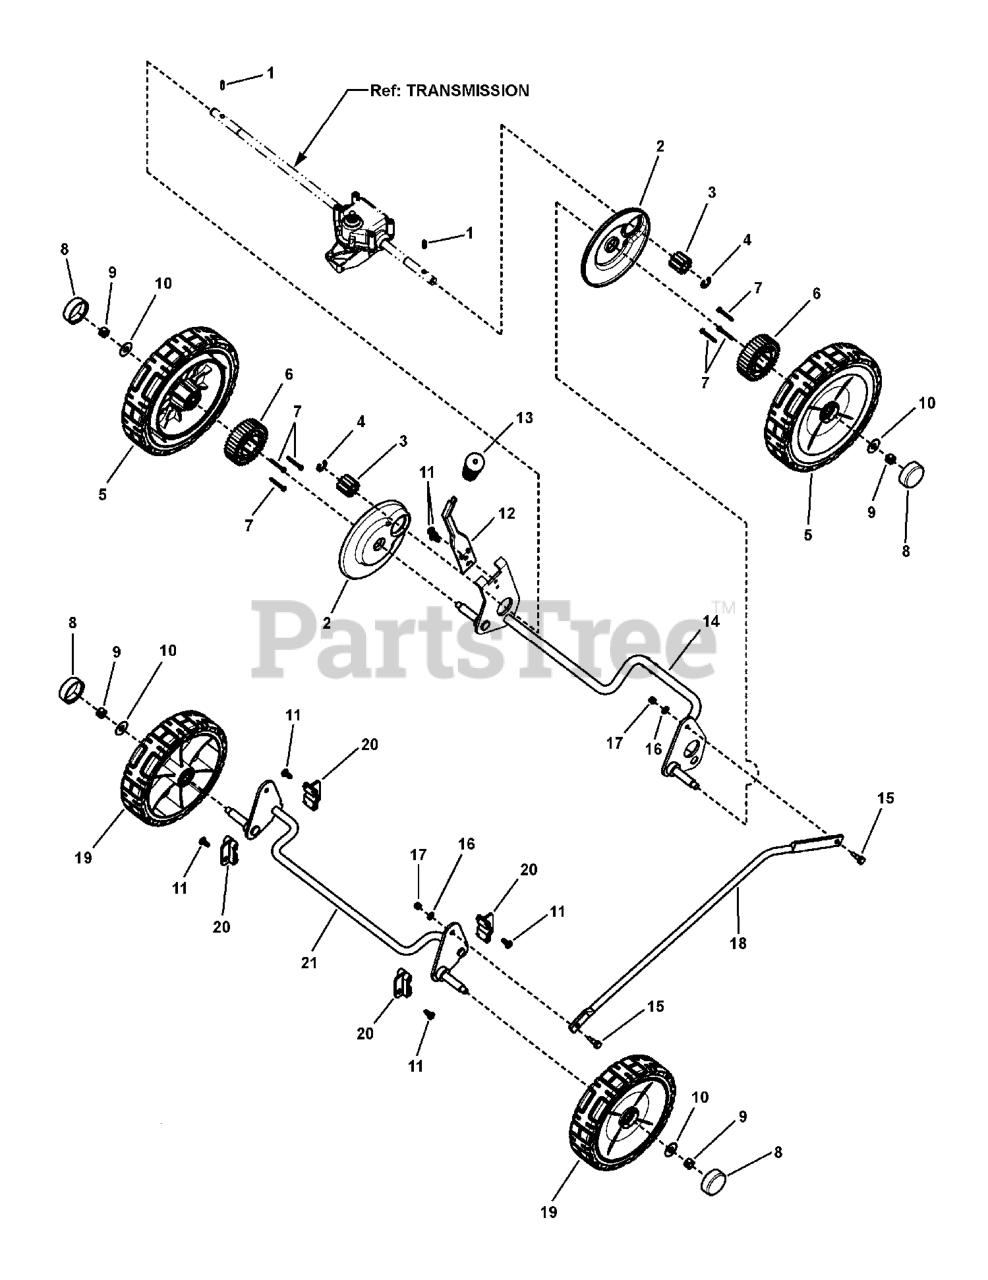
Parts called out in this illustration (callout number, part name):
1	PIN, Axle
2	SHIELD, Dust, 21" WBM, RD
3	GEAR, Pinion
4	RETAINING RING
5	ASSEMBLY, Wheel, w/Bearing 9", Charcoal Gray
6	GEAR, External Wheel
7	SCREW, #8 x 1-1/4, Hex Washer Self-Tap, Hi-Lo
8	HUBCAP, Round, Black
9	NUT, 3/8-16 Hex Center Lock, YZ
10	WASHER, 1" OD x .387 ID Flat
11	SCREW, 1/4-20 x .550 Torx Self-Tap
12	LEVER, Spring, Height-Of-Cut
13	GRIP, Height-Of-Cut
14	WELDMENT, Rear Crossbar 21" WBM, RD, YZ
15	BOLT, Shoulder, #10-24 Thread
16	WASHER, .219 x .500 x .049 Flat, BL
17	NUT, #10-24 Hex Nyloc
18	ROD, Lifter Link, 21" WBM, RD
19	ASSEMBLY, Wheel, 8 x 2 Idle, Charcoal Gray
20	BUSHING, Front 21"
21	WELDMENT, Front Crossbar 21" WBM, RD, YZ
